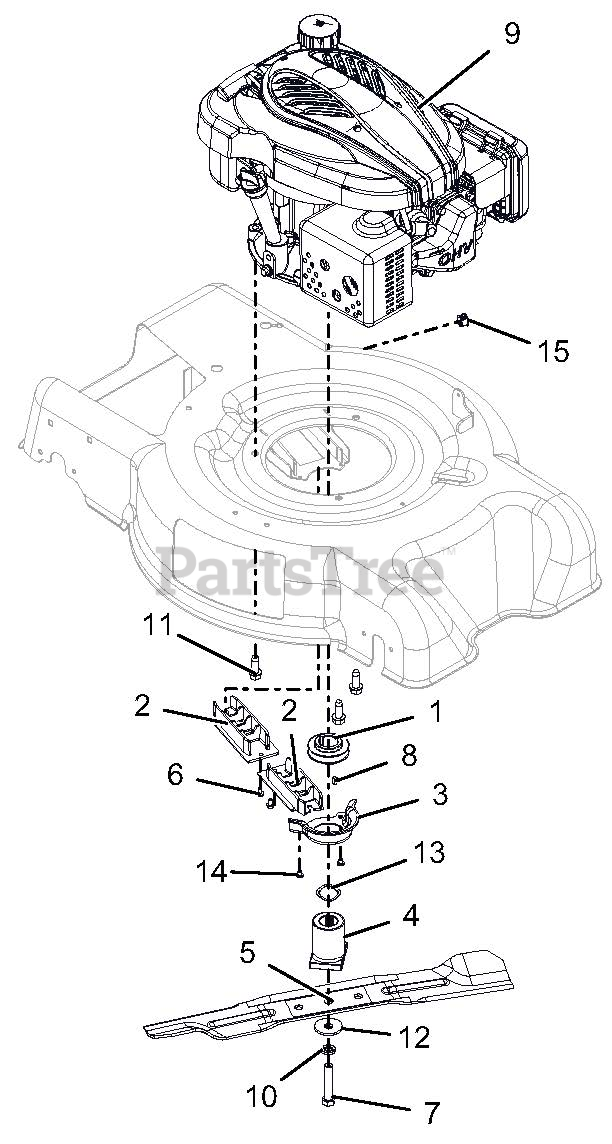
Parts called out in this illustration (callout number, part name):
1	PULLEY, GROUND DRIVE, LM
2	GUIDE, BELT INNER
3	GUIDE, BELT CRANK
4	ADAPTER, BLADE
5	BLADE, MOWER 21" HIGH LIFT
6	SCR-TAP 10-24X.375 PRE-COAT 80
7	@BLT-HEX .4375-20X2.25 GR8 YWZ
8	KEY-SQ .188X.188X.375
9	ENGINE, LONCIN 159CC VERT.
10	@WSHR-LK .44X.109 REG YWZC
11	@SCR-TAP .38-16X1.00 HWH TR YZ
12	WSHR-FL-STL .4375X1.50X.125 YZ
13	WASHER - WAVE 1.09X1.37X.016
14	SCR-TAP 10-24X.25 CRSLPH TR YZ
15	PLUG, DOME-BLACK, .625 DIA
